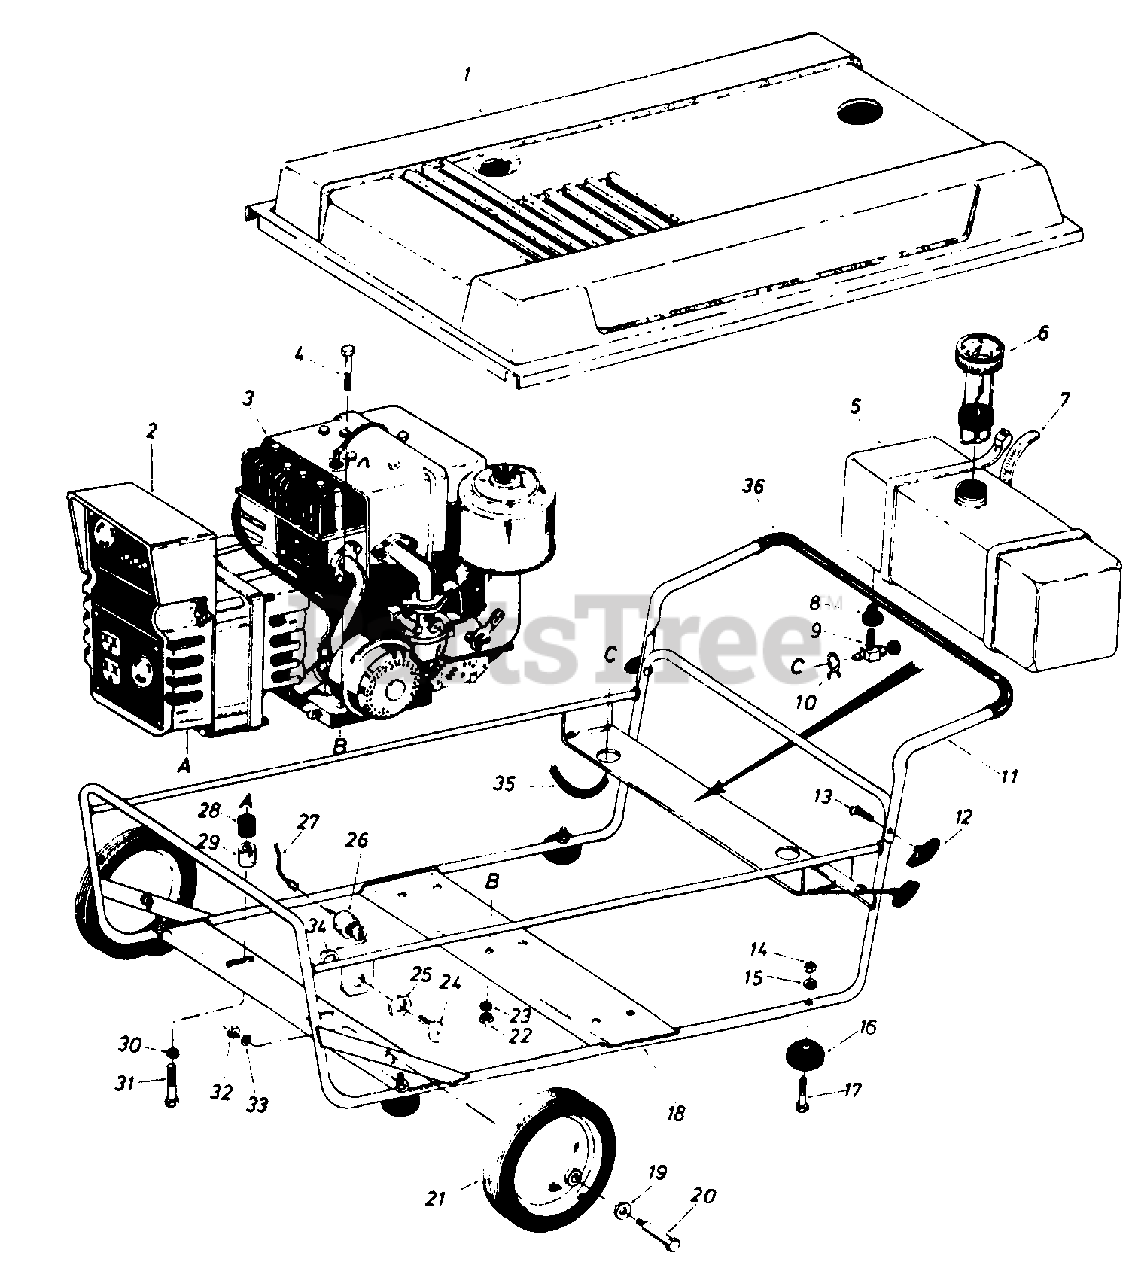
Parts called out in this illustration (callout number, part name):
1	Cover (714 and 725)
2	Generator
3	Engine
4	Hex Bolt 5/16-18 x 1.75" Lg. *
7	Cable Tie
8	Bushing
9	Fuel Shut Off Valve w/Filter
10	Hose Clamp
11	Upper Handle
12	Hand Knob
13	Curved Hd. Carriage Bolt 5/16-18 x 1.75" Lg.
14	Hex Nut 1/4-20 Thd.*
15	L.-Wash. 1/4" I.D.*
16	Rubber Bumper
17	Truss Mach. Scr. 1/4-20 x 1.75" Lg.*
18	Carriage Ass'y.
19	Fl.-Wash. .625" I.D. x .943" O.D.
20	Shoulder Bolt .623 Dia. x 2.75" Lg.
21	Wheel Assy.-Comp. 10 x 1.75
22	Hex Nut 5/16-18 Thd.*
23	L.-Wash. 5/16" I.D.*
24	Ignition Key
26	Ignition-Safety Switch
27	Electric Wire
28	Rubber Bumper
30	L.-Wash. 5/16" I.D.*
31	Hex Sems Bolt 5/16-18 x .62" Lg.
32	Hex Nut 3/8-16 Thd.*
33	L.-Wash. 3/8 " I.D.*
35	Fuel Line 29" Lg.
